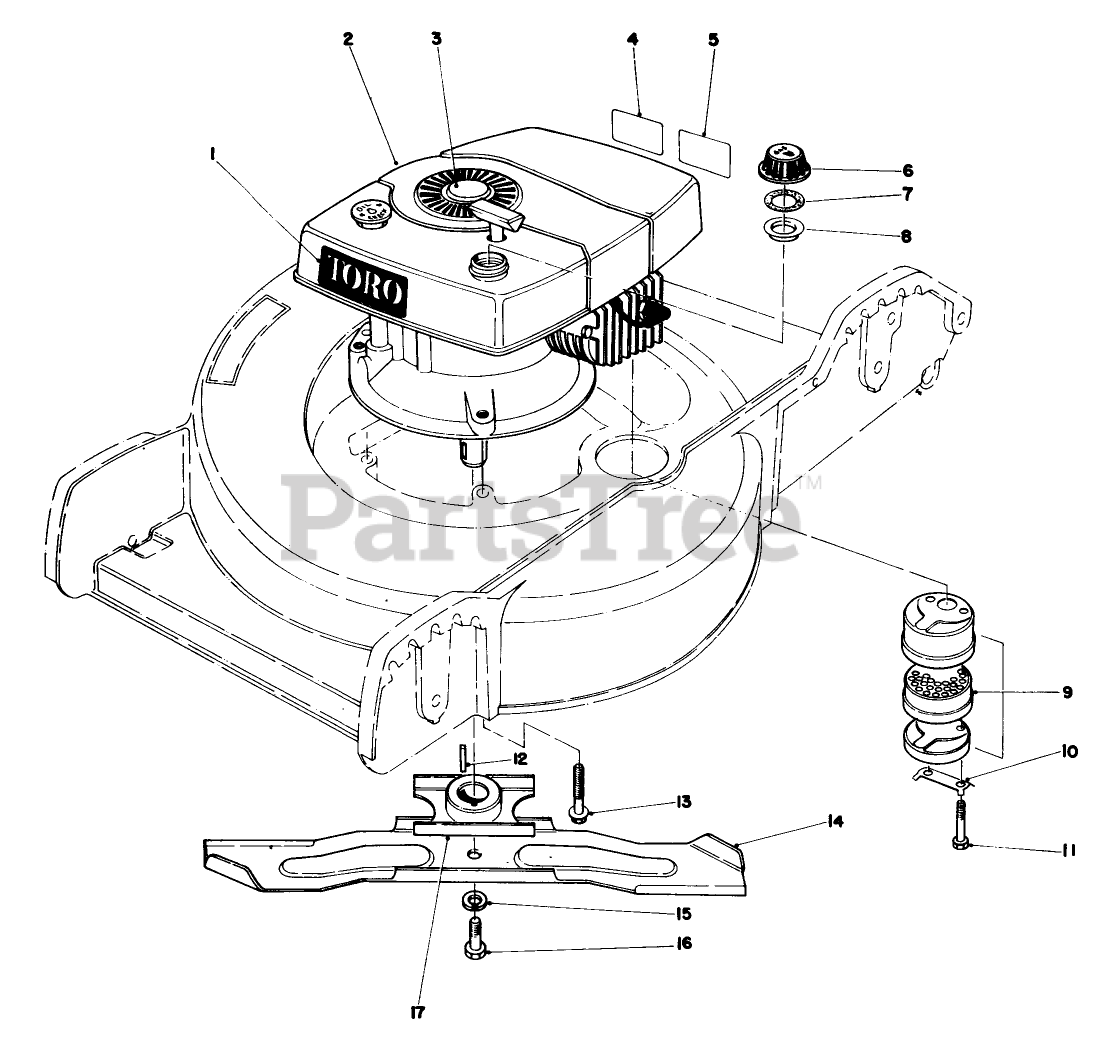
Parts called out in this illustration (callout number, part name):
1	Decal-Toro
2	Engine
3	Plug Button
4	Decal-Maintenance
5	Decal-Maintenance
6	Gas Cap (Incl. Ref. #7 & 8)
7	GASKET
8	GAS CAP BAFFLE
9	Muffler Assy. (Incl. Ref. #10 & 11)
10	CLIP - LOCKING
11	SCREW-HH
12	KEY-SQUARE
13	3/8-16 X 2 CAPSCREW
14	Blade
15	WASHER-LOCK
16	SPECIAL SCREW
17	Blade Retailer
